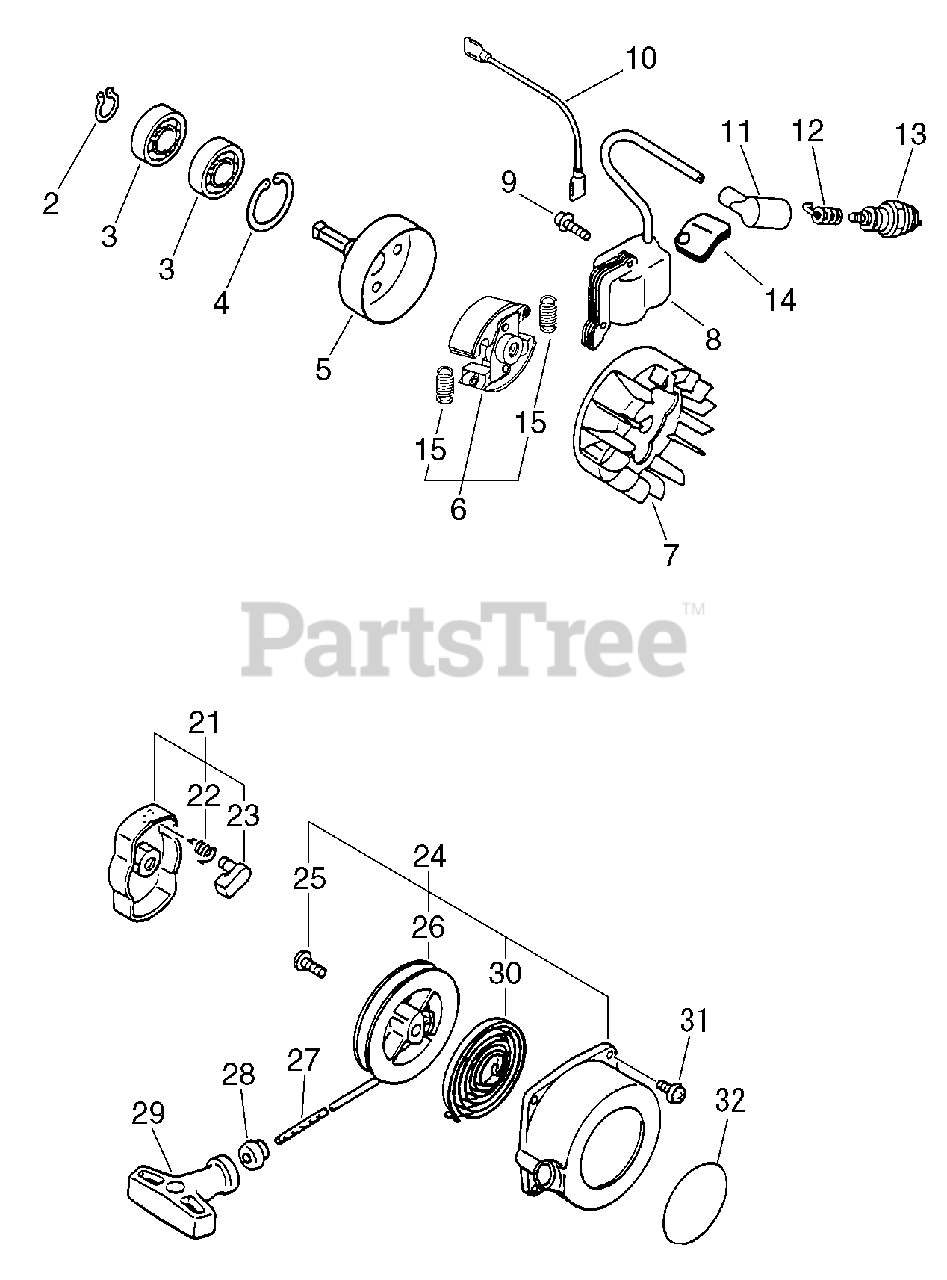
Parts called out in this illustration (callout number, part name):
2	RING, RETAINING - 12
3	BEARING, BALL - 6001
4	RING, RETAINING - 28
5	DRUM, CLUTCH
6	CLUTCH ASSY
7	FLYWHEEL
8	COIL, IGNITION
9	SCREW - 4X22
10	LEAD - IGNITION
11	CAP, SPARK PLUG
12	TERMINAL, SPARK PLUG CAP
13	SPARK PLUG -- BPM-7A
14	COVER, DUST
15	SPRING, CLUTCH
21	STARTER PAWL ASSY
22	SPRING, RETURN
23	PAWL, STARTER - BLACK
24	STARTER ASSY
26	REEL, ROPE
27	ROPE, STARTER - 3X1000
28	GUIDE, ROPE
29	GRIP, STARTER
30	SPRING, REWIND
31	SCREW - 4X16
32	LABEL - ECHO
